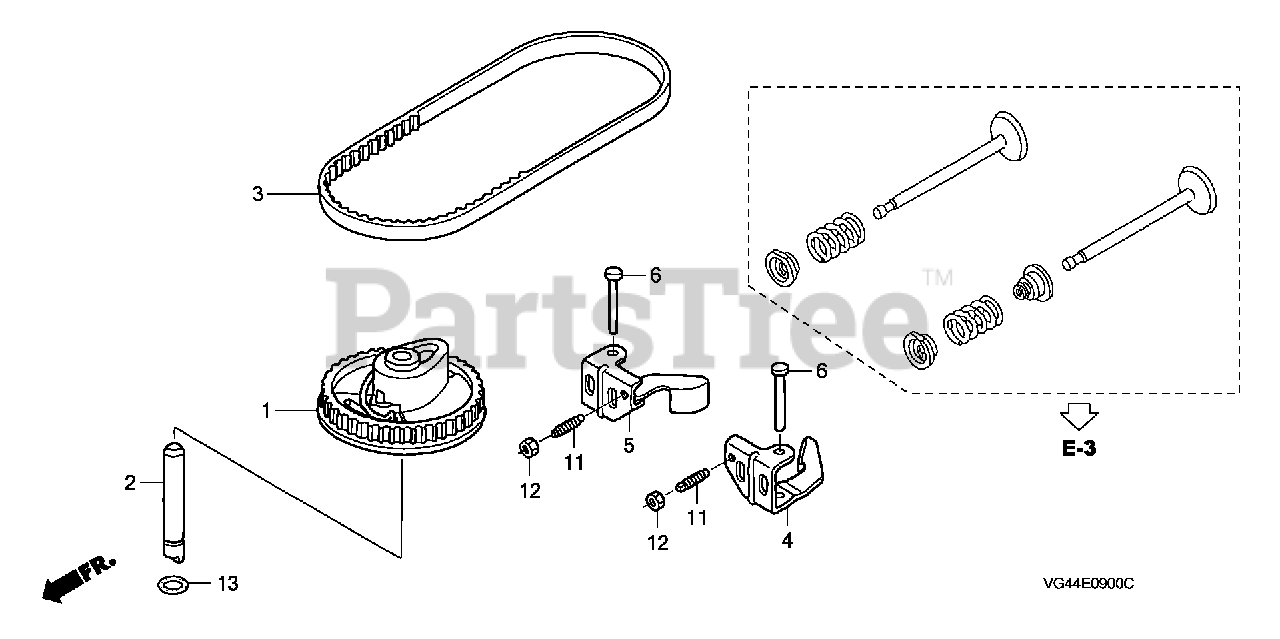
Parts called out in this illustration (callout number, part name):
1	PULLEY, CAMSHAFT
2	SHAFT, CAM PULLEY
3	BELT, TIMING (84HU7 G-200)
4	ARM, IN. VALVE ROCKER
5	ARM, EX. VALVE ROCKER
6	SHAFT, ROCKER ARM
11	SCREW, TAPPET ADJUSTING
12	NUT, TAPPET ADJUSTING
13	O-RING (6.8X1.9) (ARAI)
